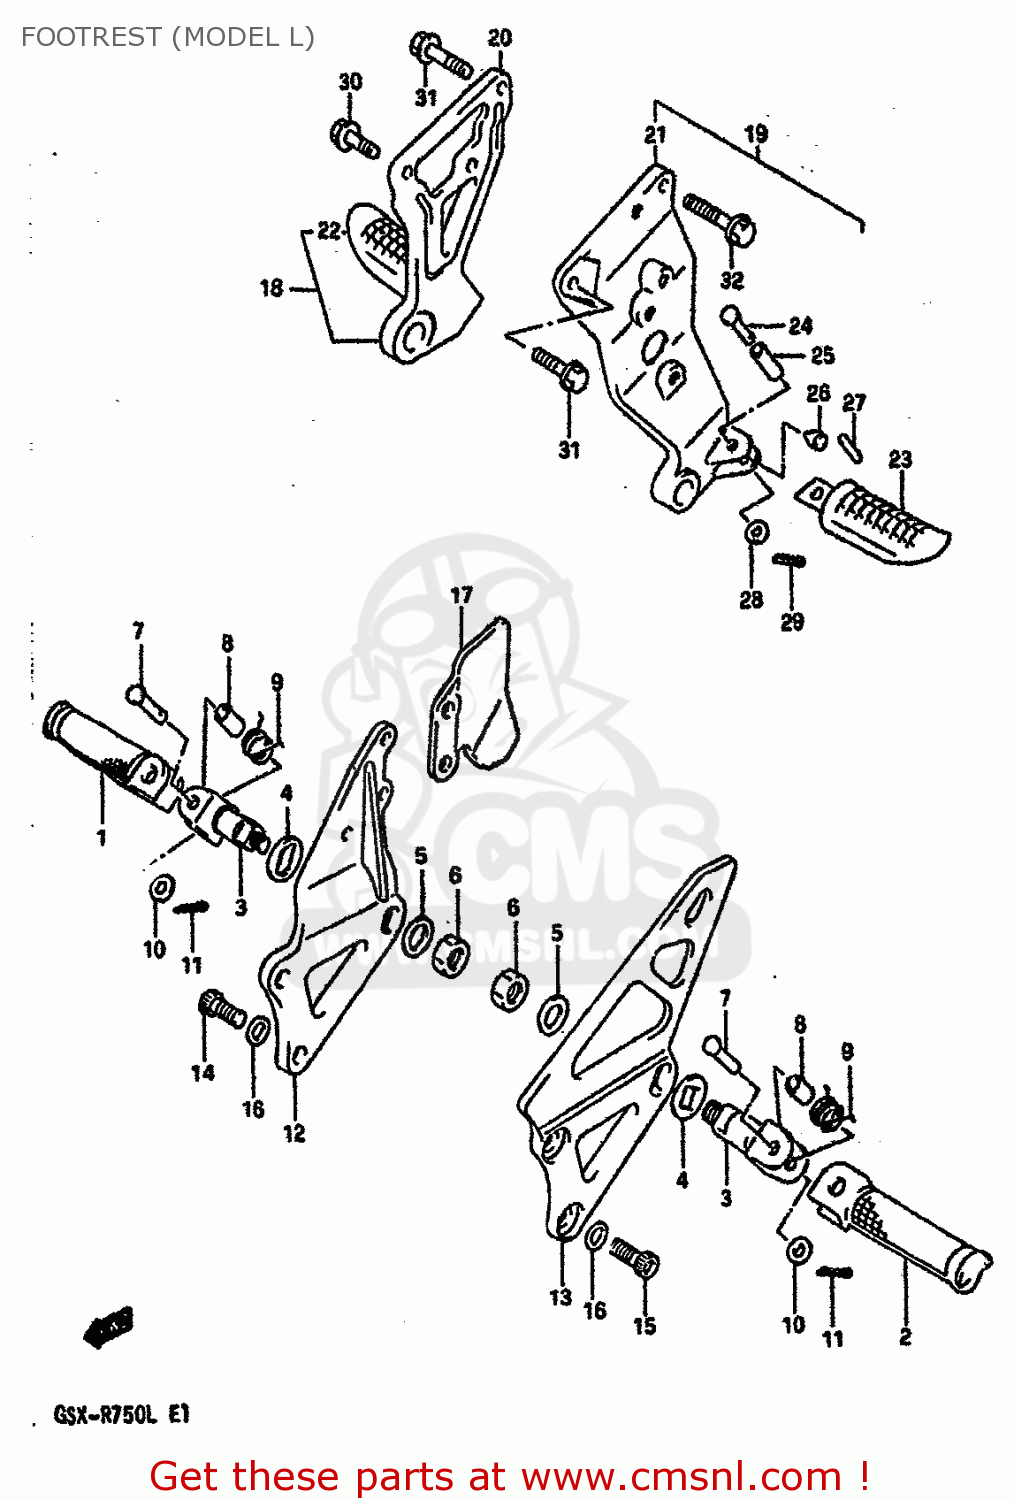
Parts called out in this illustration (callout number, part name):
1	BAR,FOOTREST,R
2	BAR,FOOTREST,L
3	BOSS,FOOTREST
4	PLATE,FOOTREST INNER
5	WASHER,FR FOOTREST
6	NUT 12MM
7	PIN
8	SPACER(8.1X12X22)
9	SPRING
10	WASHER
11	PIN 20X15
12	BAR,FRONT FOOTREST
13	BRACKET,FOOTREST,LEFT
14	BOLT,FOOTREST BRACKET
15	BOLT,FRONT FOOTREST
16	WASHER
17	GUARD,FRONT FOOTREST,RIGHT
18	FOOTREST ASSEMBLY,PILLION
19	FOOTREST ASSEMBLY,PILLION
20	BRACKET COMP,PILLION FOOT
21	BRACKET,PILLION FOOTREST
22	BAR,PILLION FOOTREST R
23	BAR,PILLION FOOTREST L
24	PIN
25	SPACER(8.1X12X22)
26	CUSHION,FOOTREST HOLDER
27	BOLT
28	BOLT
29	BOLT
30	BOLT
31	BOLT
32	BOLT
